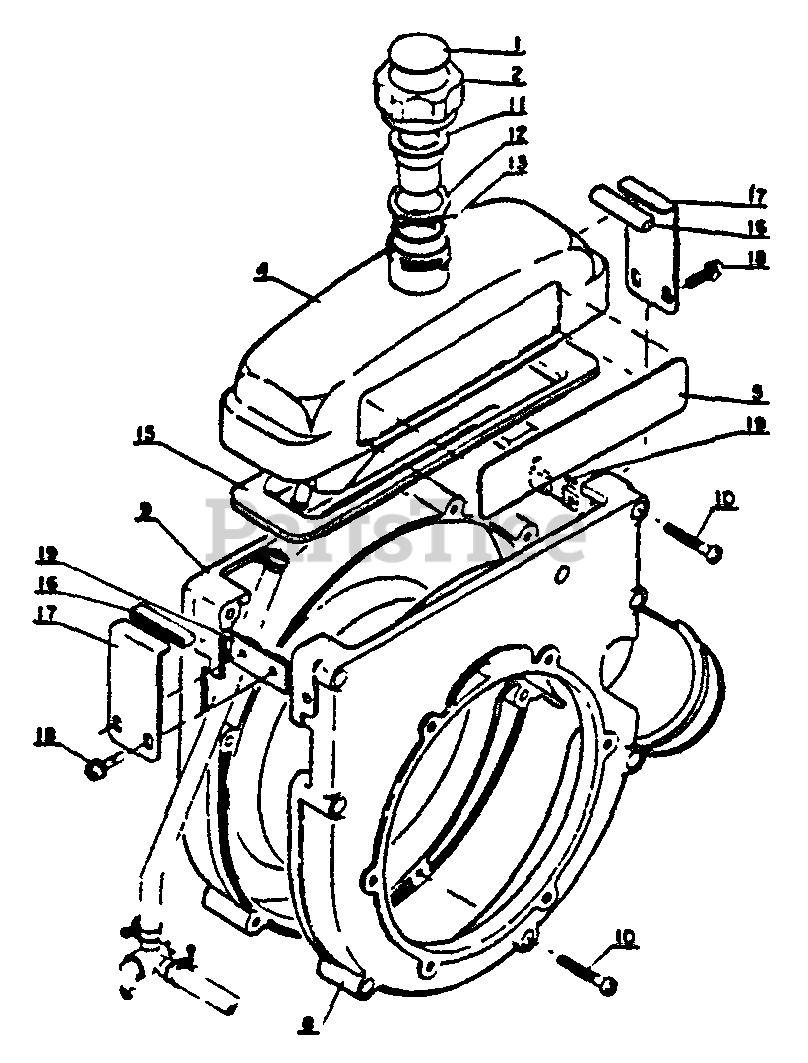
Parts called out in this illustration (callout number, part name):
1	LABEL - FUEL MIX
2	CAP
4	TANK, FUEL
5	LABEL - NAME
8	COVER, FAN - OUTER
9	COVER, FAN - INNER
10	SCREW 5×35
11	CUP ASSY
12	PACKING
13	O-RING 25 MM
15	RUBBER SEAT
16	FITTING RUBBER
17	BRACKET, FUEL TANK
18	SCREW 5×18
19	WASHER
